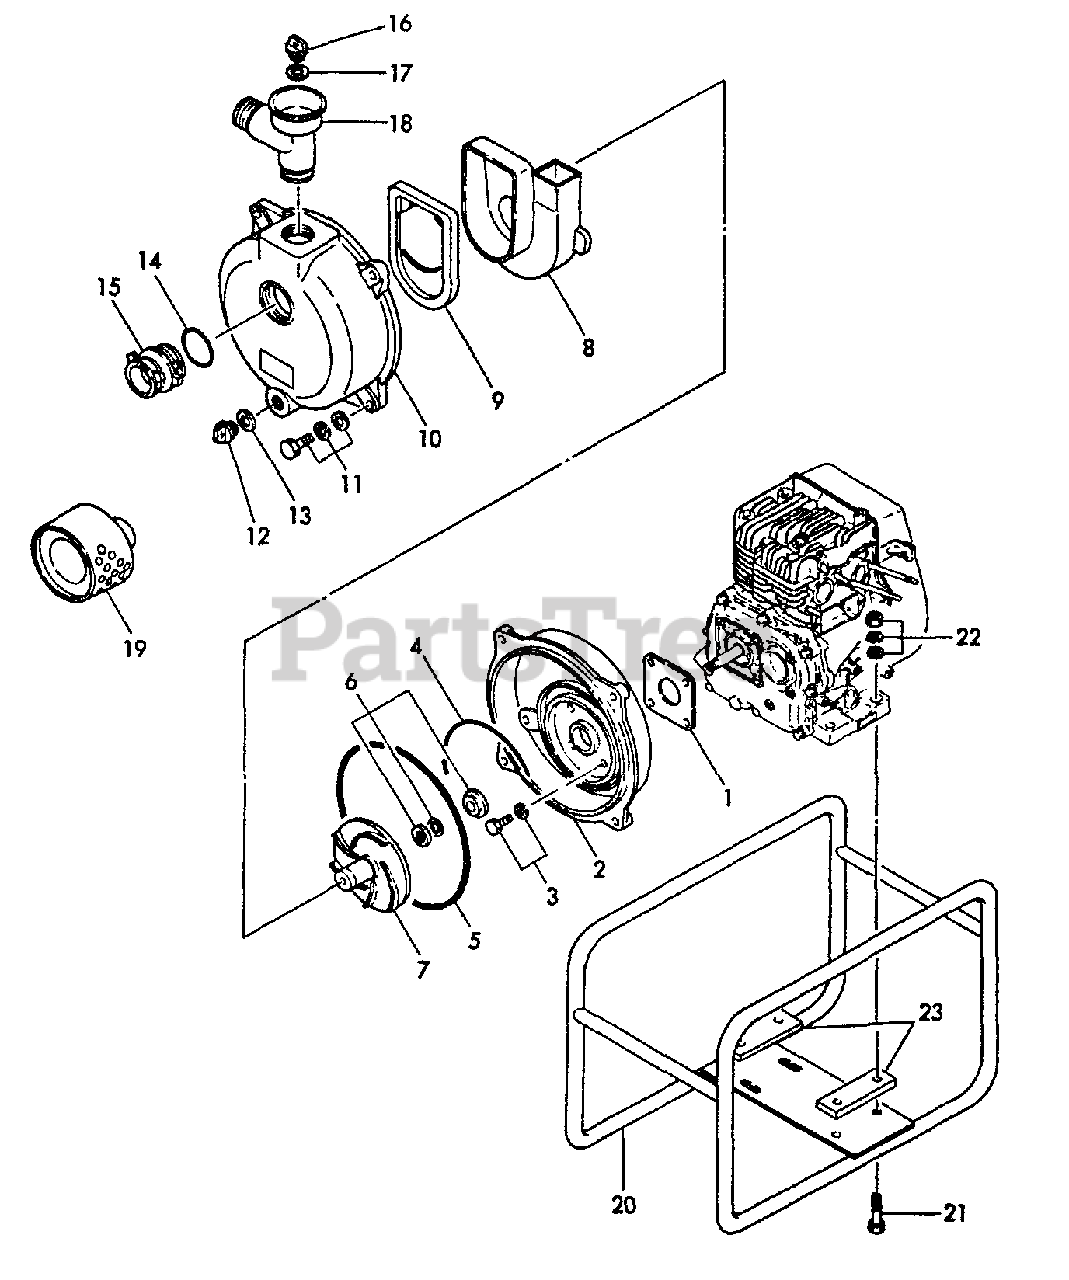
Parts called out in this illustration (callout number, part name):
1	GASKET, CASING
2	CASING
3	BOLT, CASING
4	GASKET, THREAD
5	O-RING, CASING
6	SEAL, MECHANICAL
7	IMPELLER, SHIM 0.2 Y80020000000
8	HOUSING
9	VALVE, STOP
10	COVER
11	BOLT, COVER
12	CAP, DRAIN
13	GASKET, CAP
14	O-RING, HOSE NIPPLE
15	NIPPLE, HOSE
16	CAP, DELIVERY
17	GASKET, DELIVERY
18	BEND, DELIVERY
19	STRAINER, DEBRIS
20	BASE
21	BOLT, ENGINE
22	NUT, ENGINE
23	PLATE
